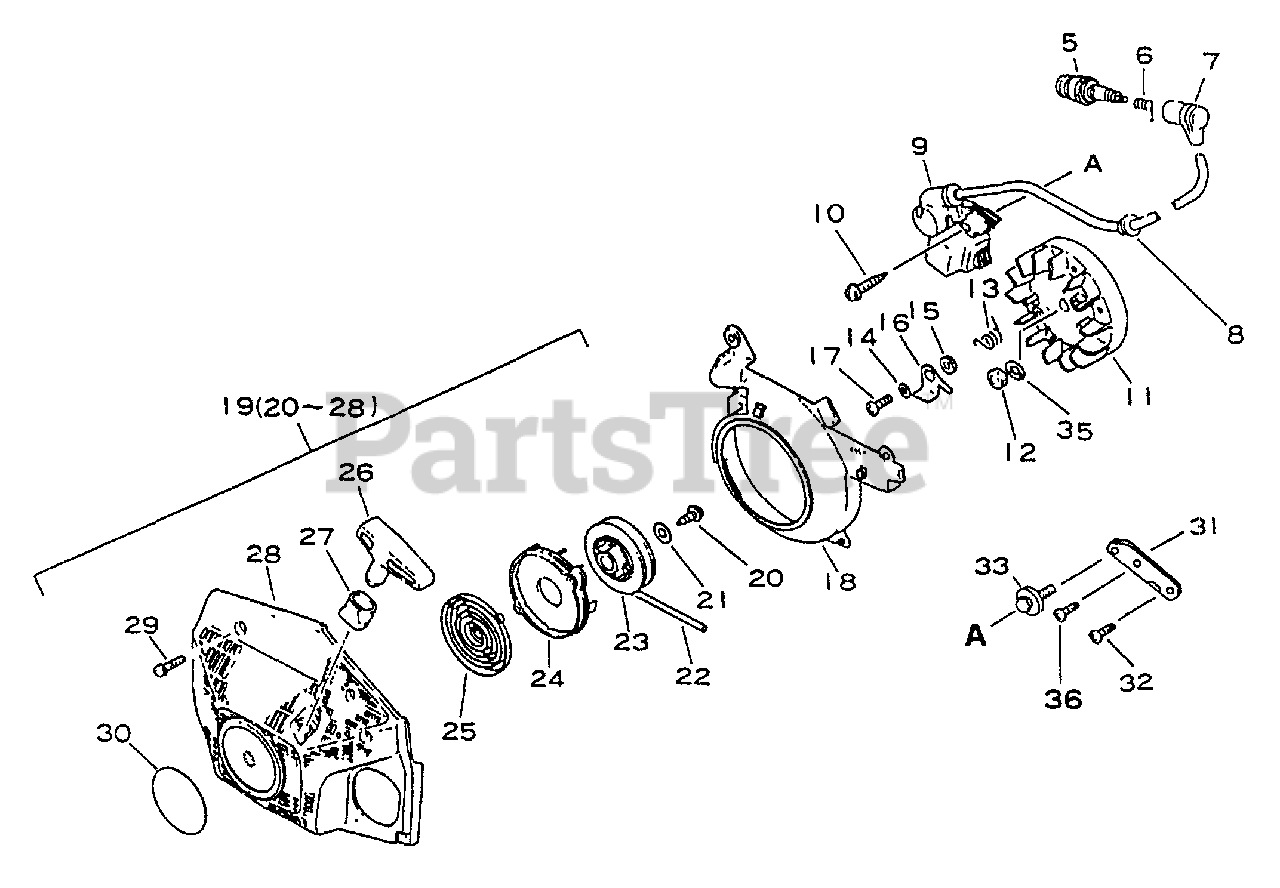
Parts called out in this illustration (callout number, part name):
5	SPARK PLUG -- CJ-6Y
6	TERMINAL, SPARK PLUG CAP
7	CAP, SPARK PLUG
8	GROMMET
9	COIL, IGNITION
10	SCREW - 4X12
11	FLYWHEEL
13	SPRING, RETURN
14	WASHER - 5
16	PAWL, STARTER
17	SCREW - 5X14
18	SHIELD, FAN
19	STARTER ASSY
20	SCREW - 5X14
21	WASHER - 5
22	ROPE, STARTER
23	REEL, ROPE
24	PLATE, STARTER
25	SPRING, REWIND
26	GRIP, STARTER
27	GUIDE, ROPE
28	CASE, STARTER
29	SCREW - 5X20
30	LABEL - ECHO
31	TERMINAL - GROUND
32	SCREW - 4X8
34	WASHER - 4
35	LOCKWASHER - 8
36	SCREW - 4X6
